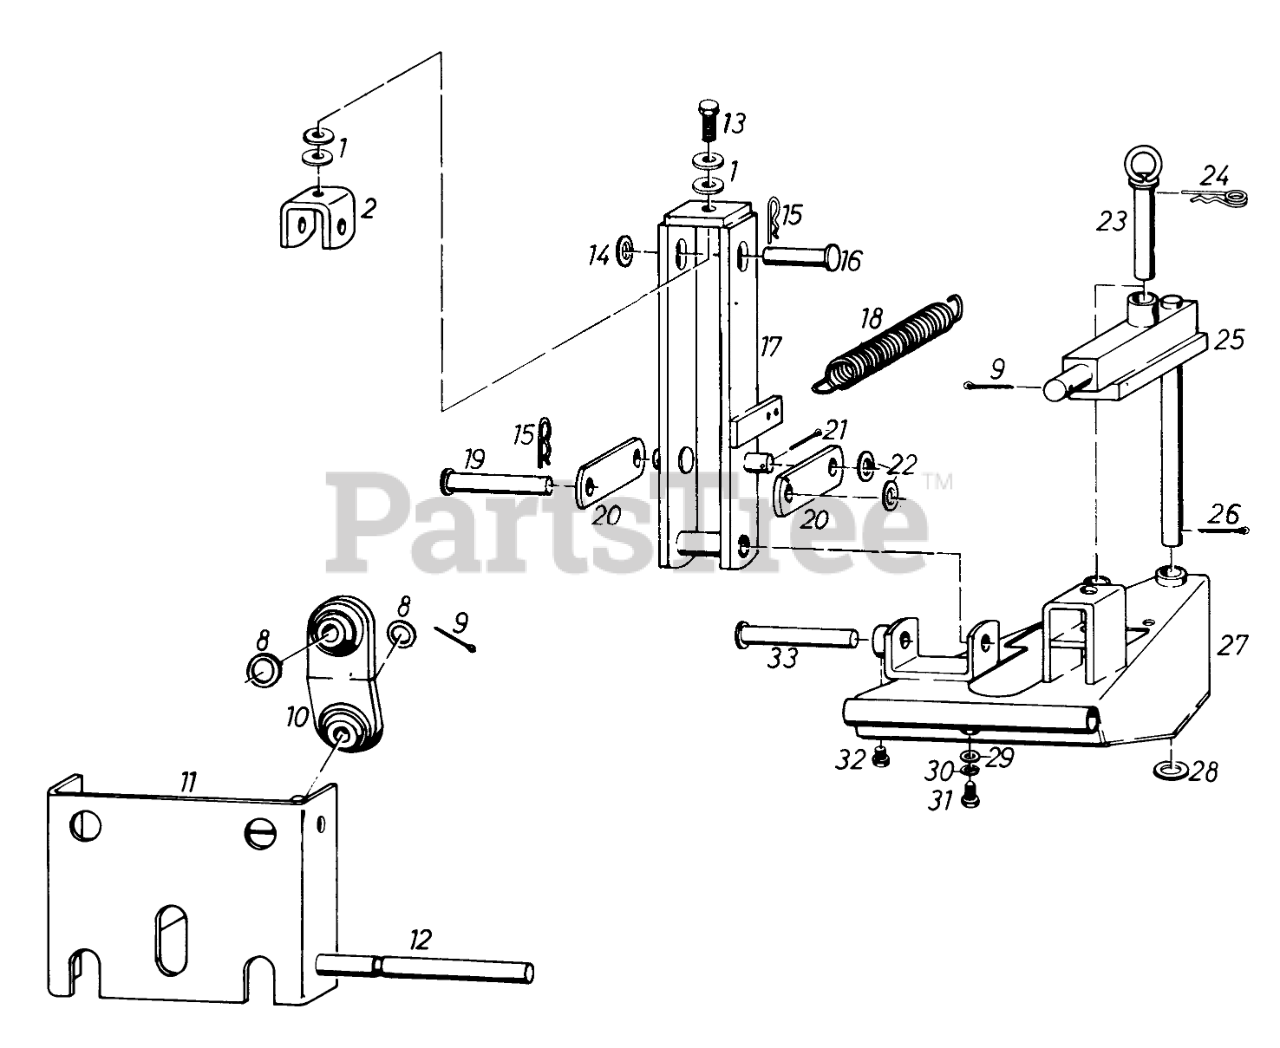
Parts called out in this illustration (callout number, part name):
1	Washer
2	Bracket
9	Cotter Pin
10	Joint
11	Support Plate
12	Mounting Rod
14	Washer
15	Hairpin Cotter
16	Clevis Pin
17	Lift Bracket
18	Spring
19	Clevis Pin
20	Guide Plate
22	Washer
23	Centering Pin
24	Hairpin Cotter
25	Swing Shaft Assembly
26	Bracket
27	A-Frame
28	Washer
29	Washer
30	Lockwasher
33	Clevis Pin
